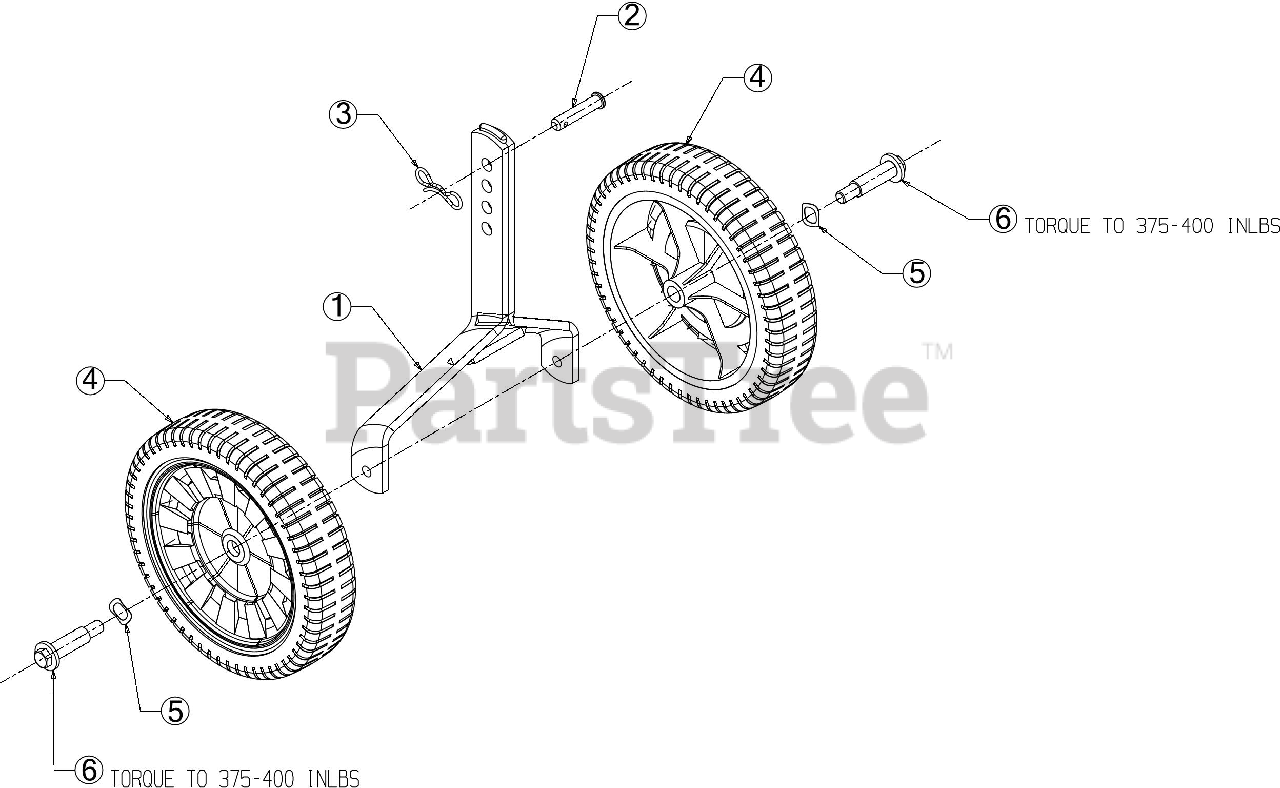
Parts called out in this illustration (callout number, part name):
1	WHEEL BRACKET ASSEMBLY
2	CLEVIS PIN .375 x .1.75
3	PIN:COTTER
4	WHEEL-8IN
5	WAVE WASHER
6	SHOULDER SCREW .496X1.44 3/8-16
